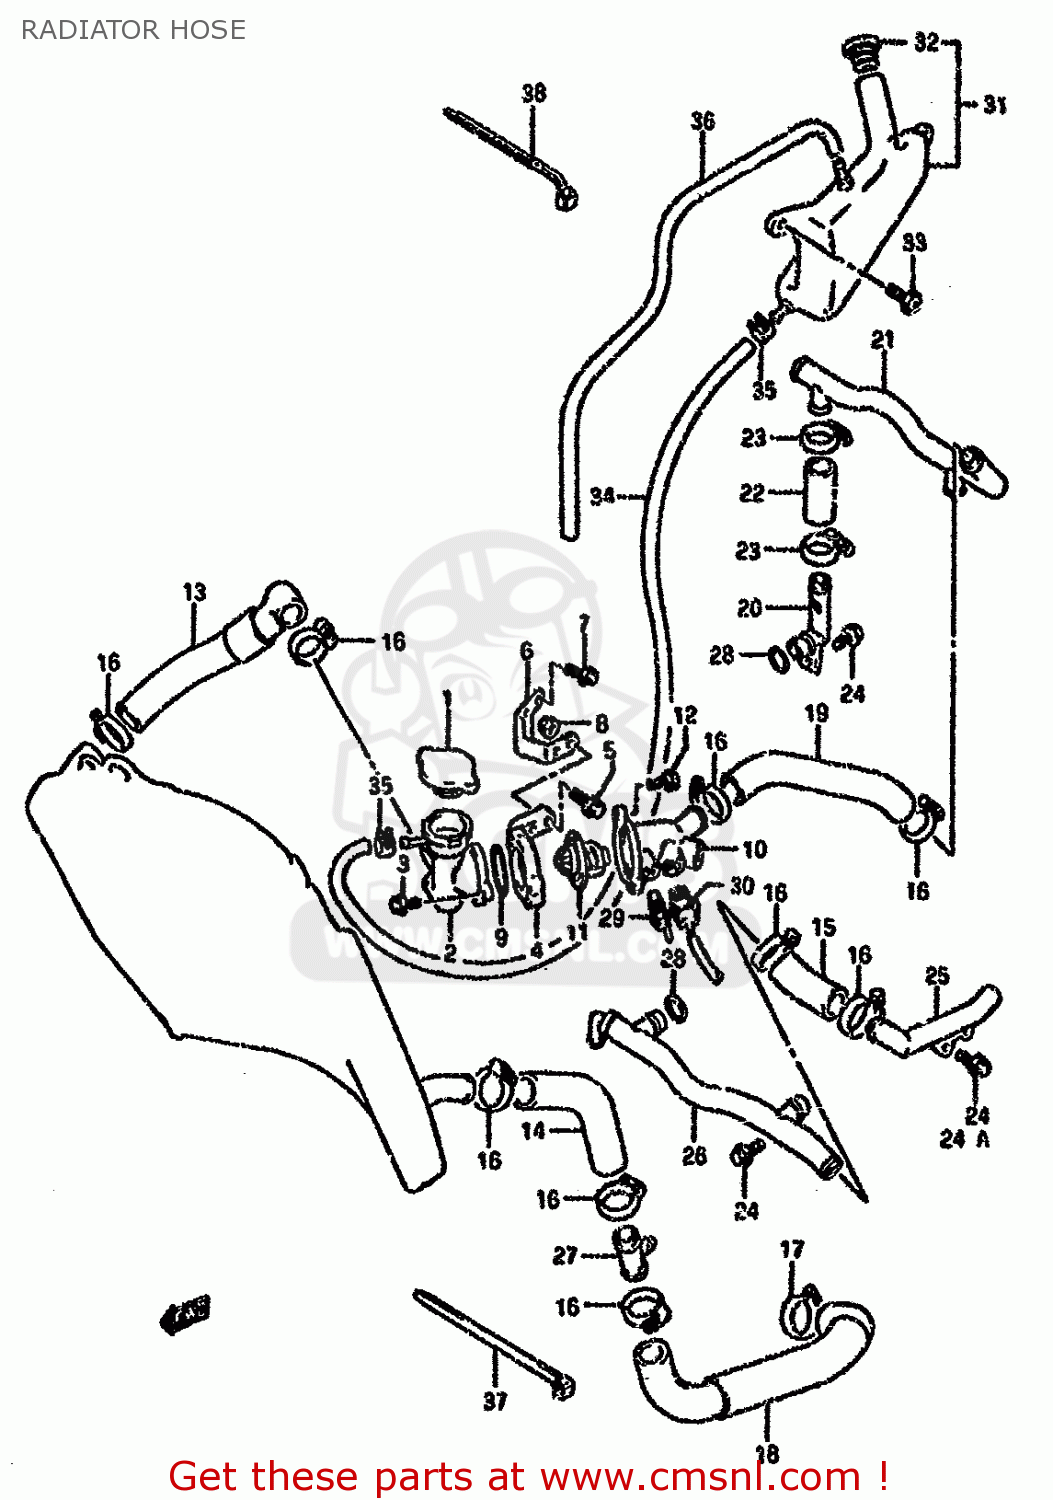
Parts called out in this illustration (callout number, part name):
1	CAP,RADIATOR
2	CONDUCTION,RADIATOR
3	BOLT
4	BRACKET,CONDUCTION
5	BOLT
6	BRACKET,CONDUCTION BRAKE
7	BOLT
8	NUT
9	O RING(D:2.4,ID:43.2)
10	CONNECTOR,THERMOSTAT INLET
11	THERMOSTAT,WATER
12	BOLT
13	HOSE,WATER
14	HOSE,RADIATOR OUTLET
15	HOSE,WATER
16	CLAMP
17	CLAMP
18	HOSE,WATER PUMP INLET
19	HOSE,HEAD OUTLET
20	PIPE,HEAD OUTLET
21	PIPE COMP,HEAD OUTLET
22	HOSE,RADIATOR JOINT NO.1
23	CLAMP
24	BOLT
24A	BOLT(6X36)
25	PIPE,CYLINDER SIDE
26	PIPE,CYLINDER INLET
27	UNION,HOSE JOINT
28	O RING(D:3.2,ID:17.8)
29	GAUGE ASSY,WATER TEMP
30	SWITCH COMP,RADIATOR FAN
31	TANK ASSY,RESERVOIR
32	CAP,RESERVOIR TANK
33	SCREW(6X20)
34	HOSE,RESERVOIR TANK INLET
35	CLIP
36	HOSE,RESERVOIR TANK OVERFLOW
37	CLAMP
38	CLAMP(L:165)
